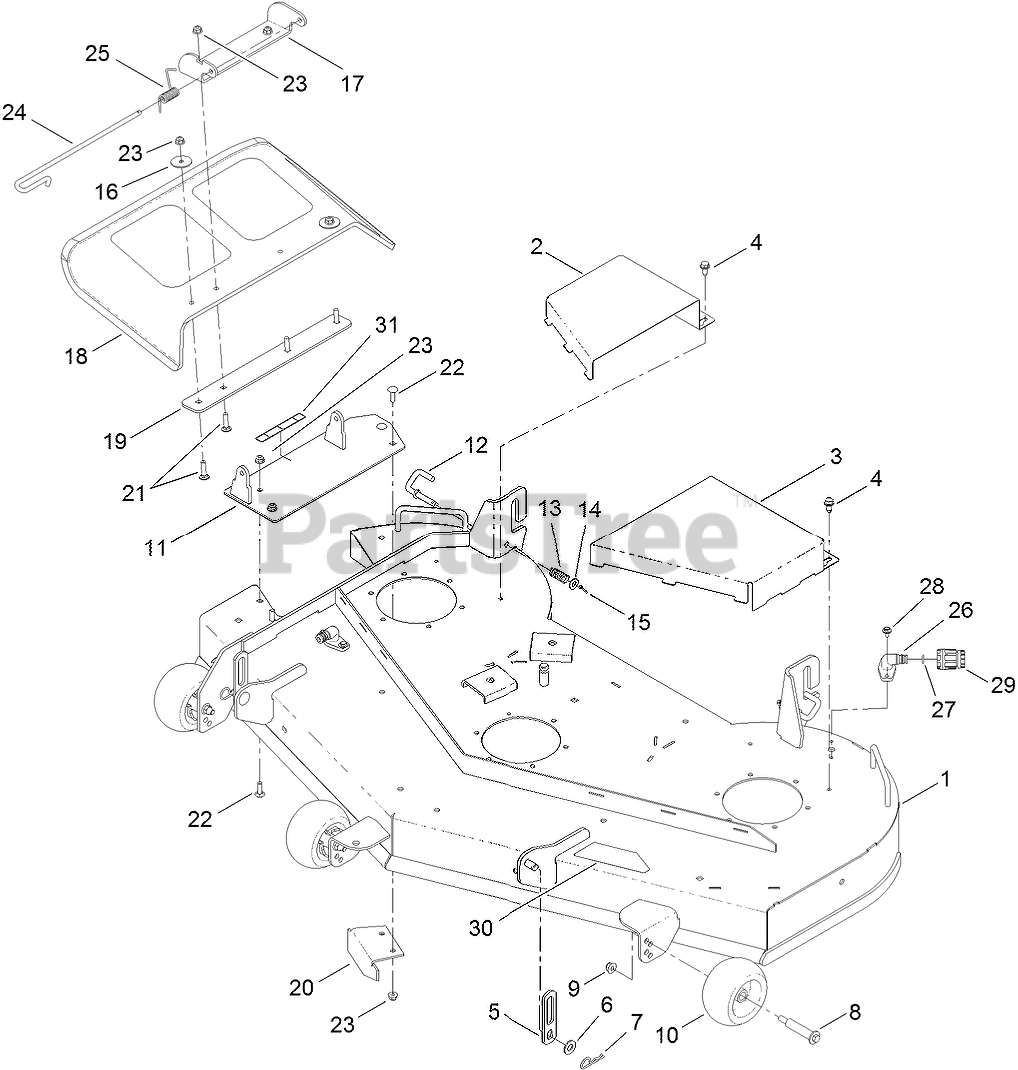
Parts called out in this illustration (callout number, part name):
1	54 INCH DECK ASM
2	COVER-BELT, RH
3	COVER-BELT, LH
4	SCREW-HWHTF
5	LINK-LIFT
6	WASHER-FLAT
7	PIN-COTTER
8	BOLT-SHOULDER
9	NUT-HF, NI
10	ROLLER-SCALP, ANTI
11	PLATE-COVER
12	PIN-LATCH
13	SPRING-COMPRESSION
14	WASHER-FLAT
15	PIN-COTTER
16	WASHER-FLAT
17	BRACKET-DEFLECTOR, UPPER
18	DEFLECTOR
19	PLATE-DEFLECTOR
20	BAFFLE-CUTOFF
21	SCREW-CARR
22	SCREW-CARR
23	NUT-HF, NI
24	PIN-CHUTE
25	SPRING-TORSION
26	FITTING-WASHOUT
27	O-RING
28	SCREW-HHFTF
29	CONNECTOR-HOSE
31	DECAL-DANGER
